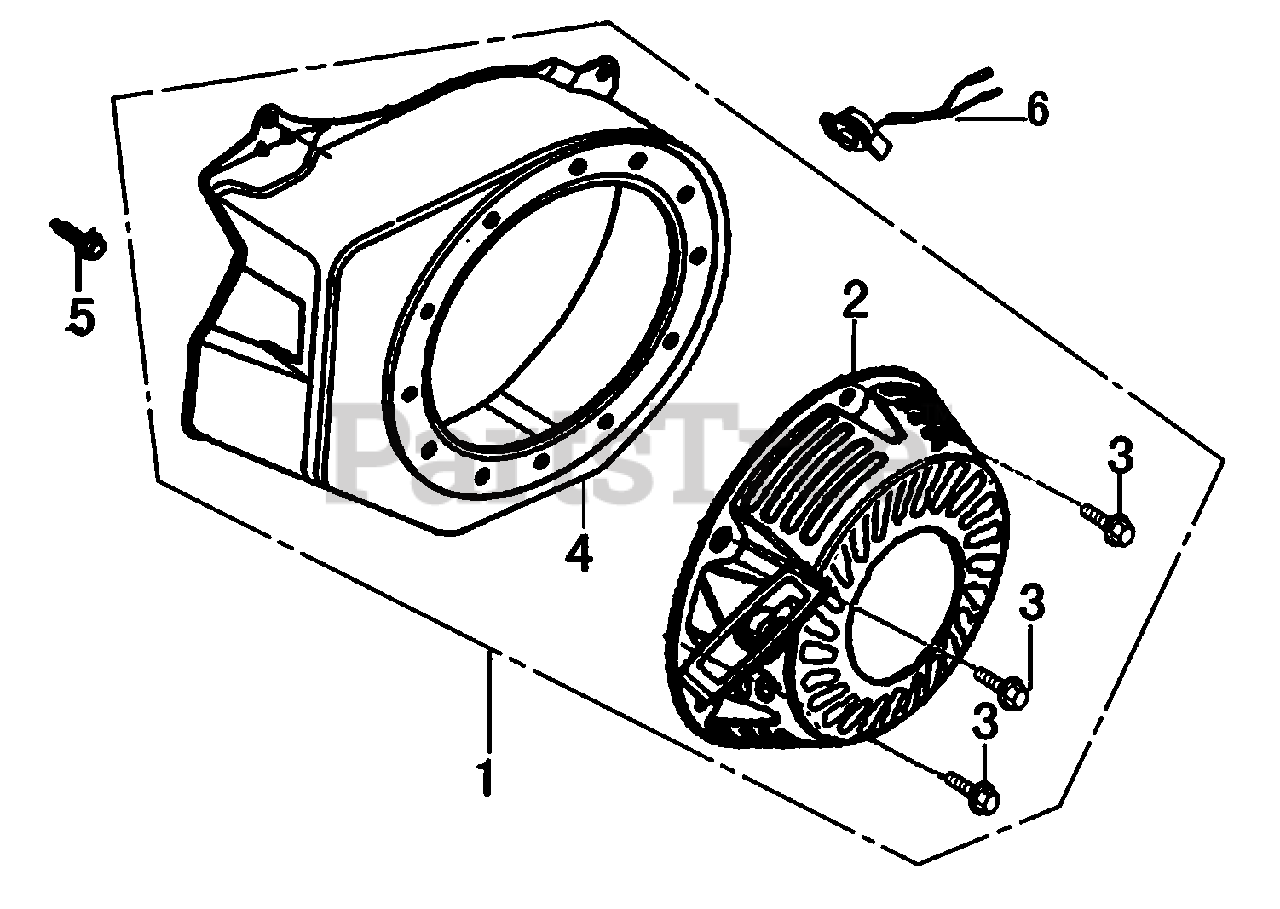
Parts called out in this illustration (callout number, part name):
1	STARTER, RECOIL W/ BLWR HSNG
2	STARTER ASSY., RECOIL
3	BOLT, FLANGE
4	COVER, FAN
5	BOLT, FLANGE
6	SWITCH ASSY., ENGINE STOP
